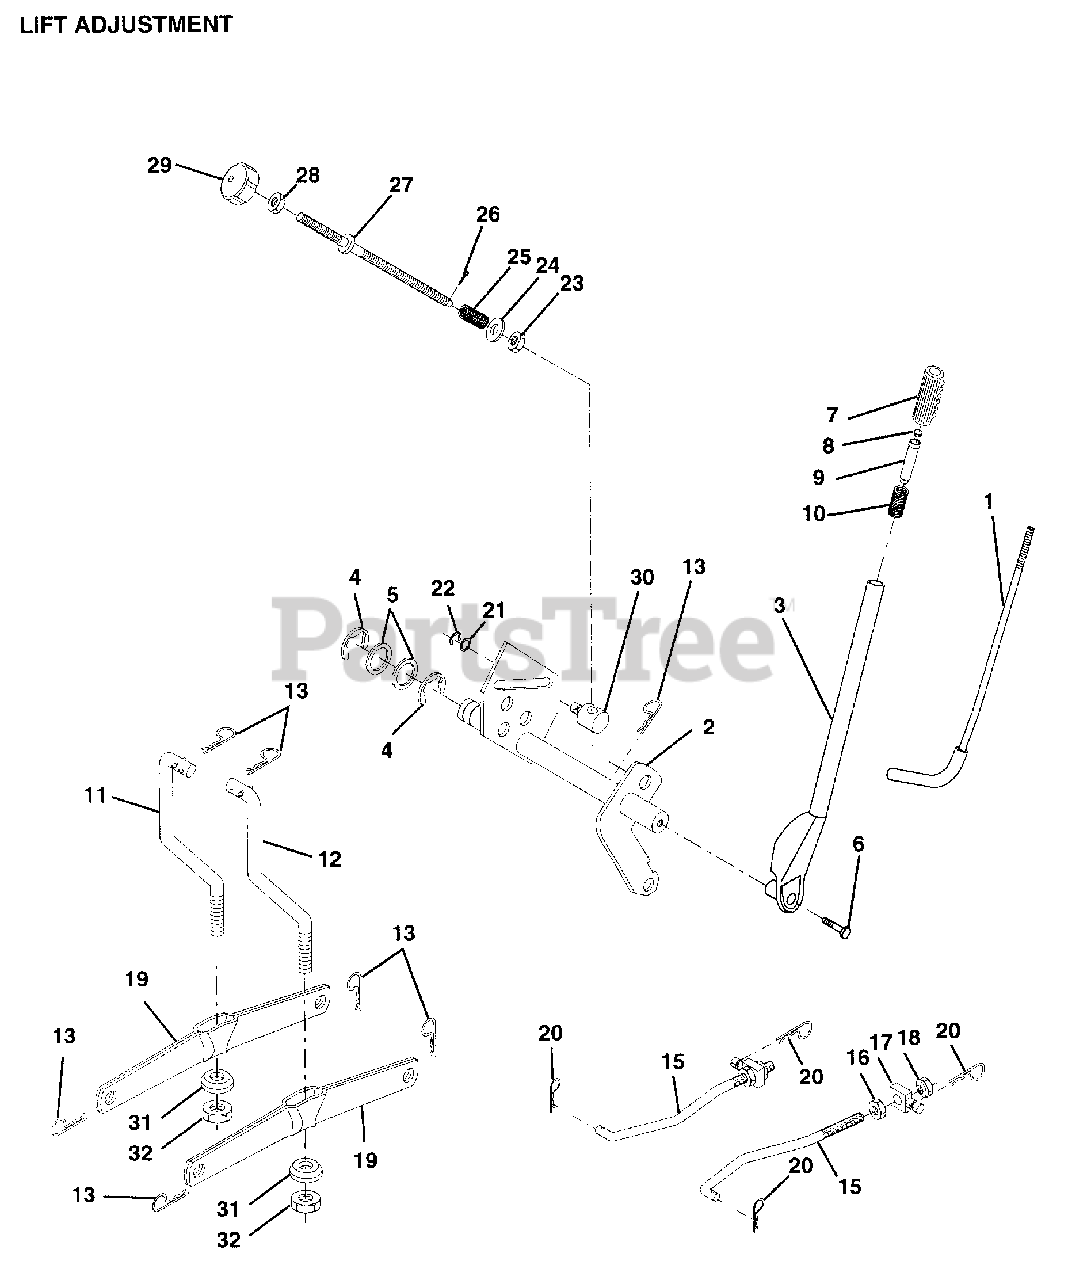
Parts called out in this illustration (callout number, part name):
1	LEVER ROD LT
2	SHAFT LIFT W/IND
4	E-RING
5	WASHER
6	"BOLT,HEX"
7	GRIP
10	SPRING T
11	LINK LIFT LH
12	LINK LIFT RH
15	LINK.FRONT
16	NUT
17	TRUNION
18	NUT.LK.W/WSH.1/2.
19	ARM SUSP REAR
20	RETAINER.SPRING
21	WASHER
22	KLIP RING
23	NUT T
24	WASHER
25	SPRING T
27	ROD LIFT LT
28	NUT
29	KNOB INF 3/8-16
30	TRUNION LT
31	BEARING PVT LH
32	NUT.LOCK.3/8-24
